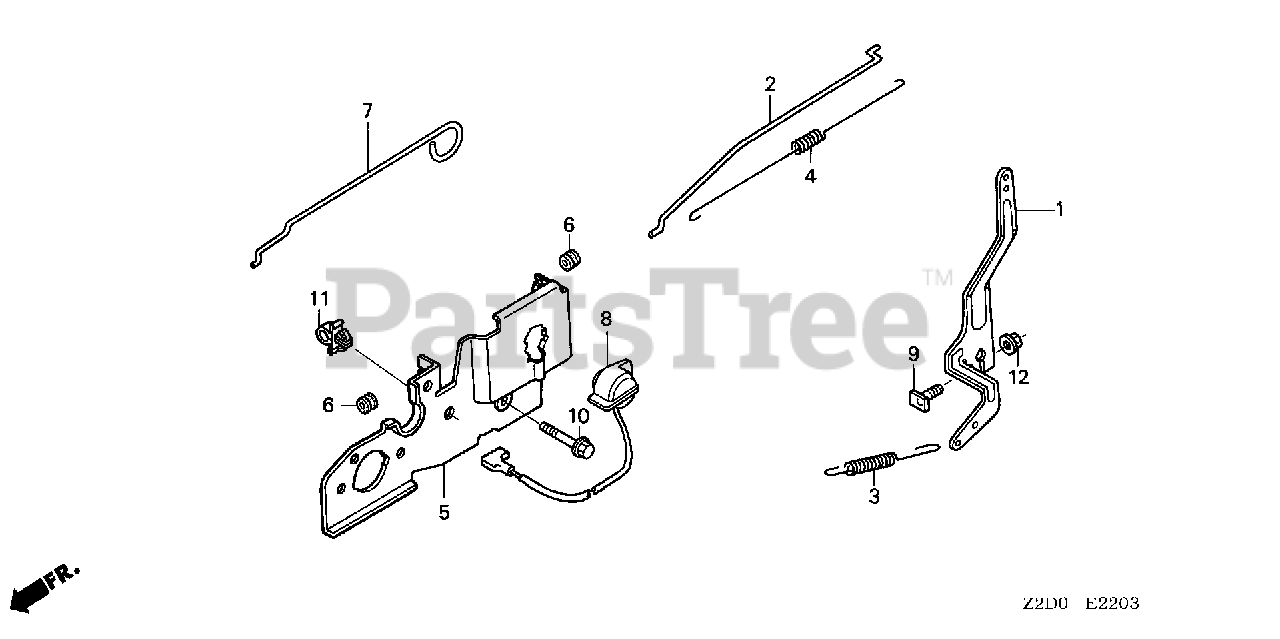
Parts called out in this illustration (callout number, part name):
1	ARM, GOVERNOR
2	ROD, GOVERNOR
3	SPRING, GOVERNOR
4	SPRING, THROTTLE RETURN
5	BASE, CONTROL
6	GROMMET, CHOKE ROD
7	ROD, CHOKE
8	SWITCH ASSY., ENGINE STOP
9	BOLT, GOVERNOR ARM
10	BOLT, FLANGE (6X45) (CT200)
11	CLIP A, CABLE (3.8MM BLACK) (NIFCO)
12	NUT, FLANGE (6MM)
